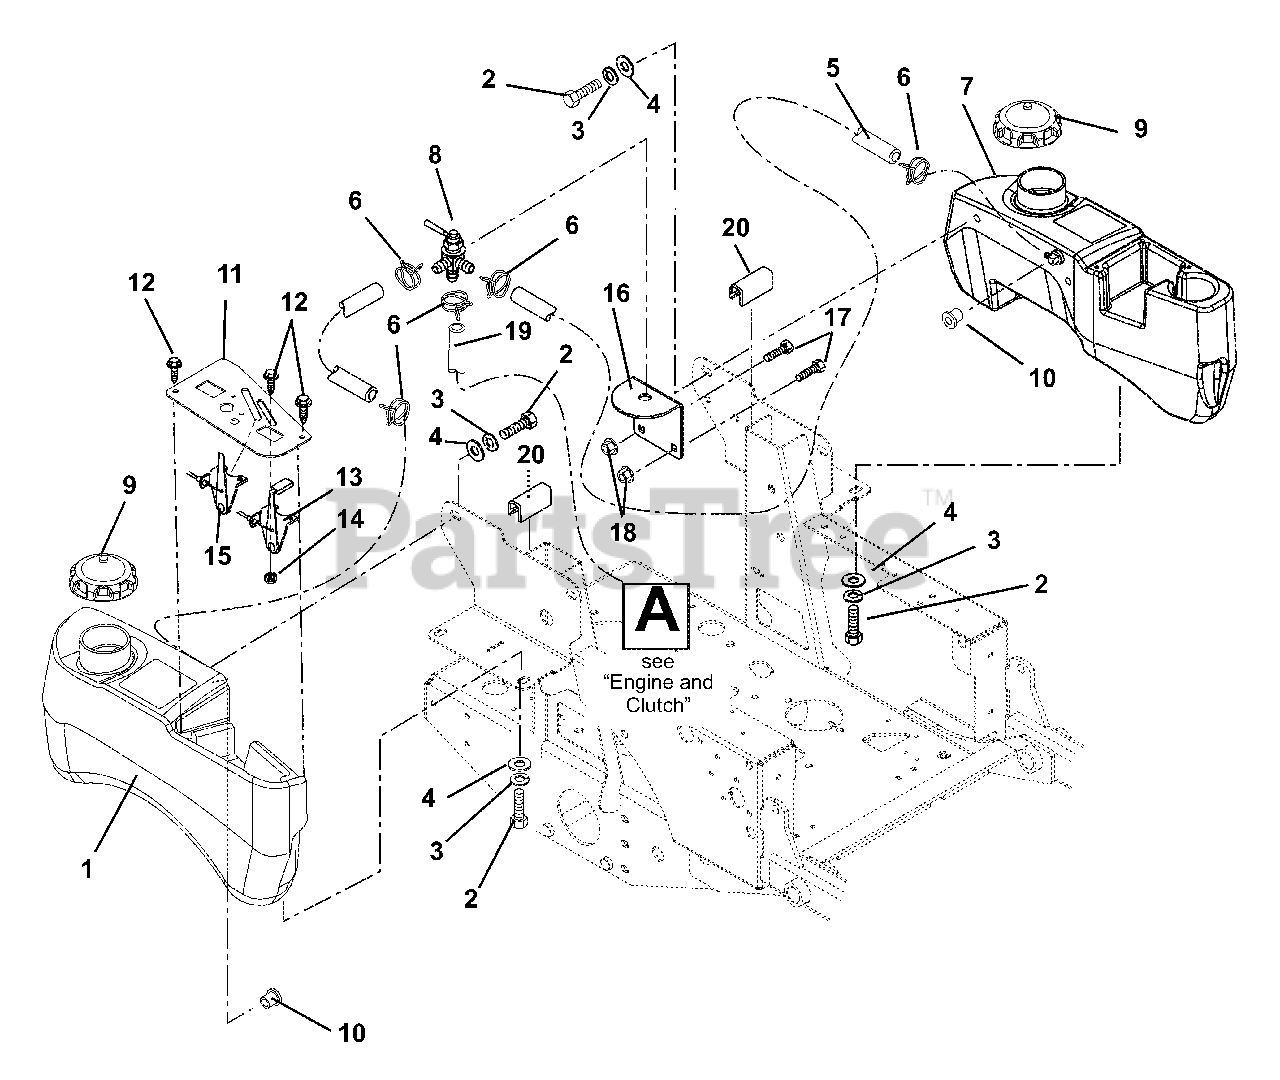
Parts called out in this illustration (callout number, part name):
1	TANK, FUEL RH W/O HOSE
2	@BLT-HEX .31-18X.75 GR5 YWZC
3	@WSHR-LK .31X.078 REG YWZC
4	@WSHR-FL-STL.38X.875X.083 YWZC
5	HOSE, 5.75"-1/4" ID GAS LINE
6	CLAMP-HOSE WIRE .490/.510X.116
7	TANK, LH FUEL CZ W/O HOSE
8	VALVE, FUEL
9	CAP - FUEL
10	BSHG-FLG .375 X 1.062 X .625 R
11	PANEL, CONTROL
12	@SCR-MCH 10-24X.50 HWH YWZC
13	CABLE, THROTTLE-CHOKE
14	@NUT-LK-NYL 10-24 W/INSRT YWZC
15	CABLE, CHOKE
16	BRKT, FUEL VALVE MNTG
17	@BLT-RDHDSQNK .31-18X.75 G5YZ
18	@NUT-LK-TOP-FLG .31-18 YWZC
19	HOSE, 29"-1/4"ID GAS LINE
20	STRIP, COWL
